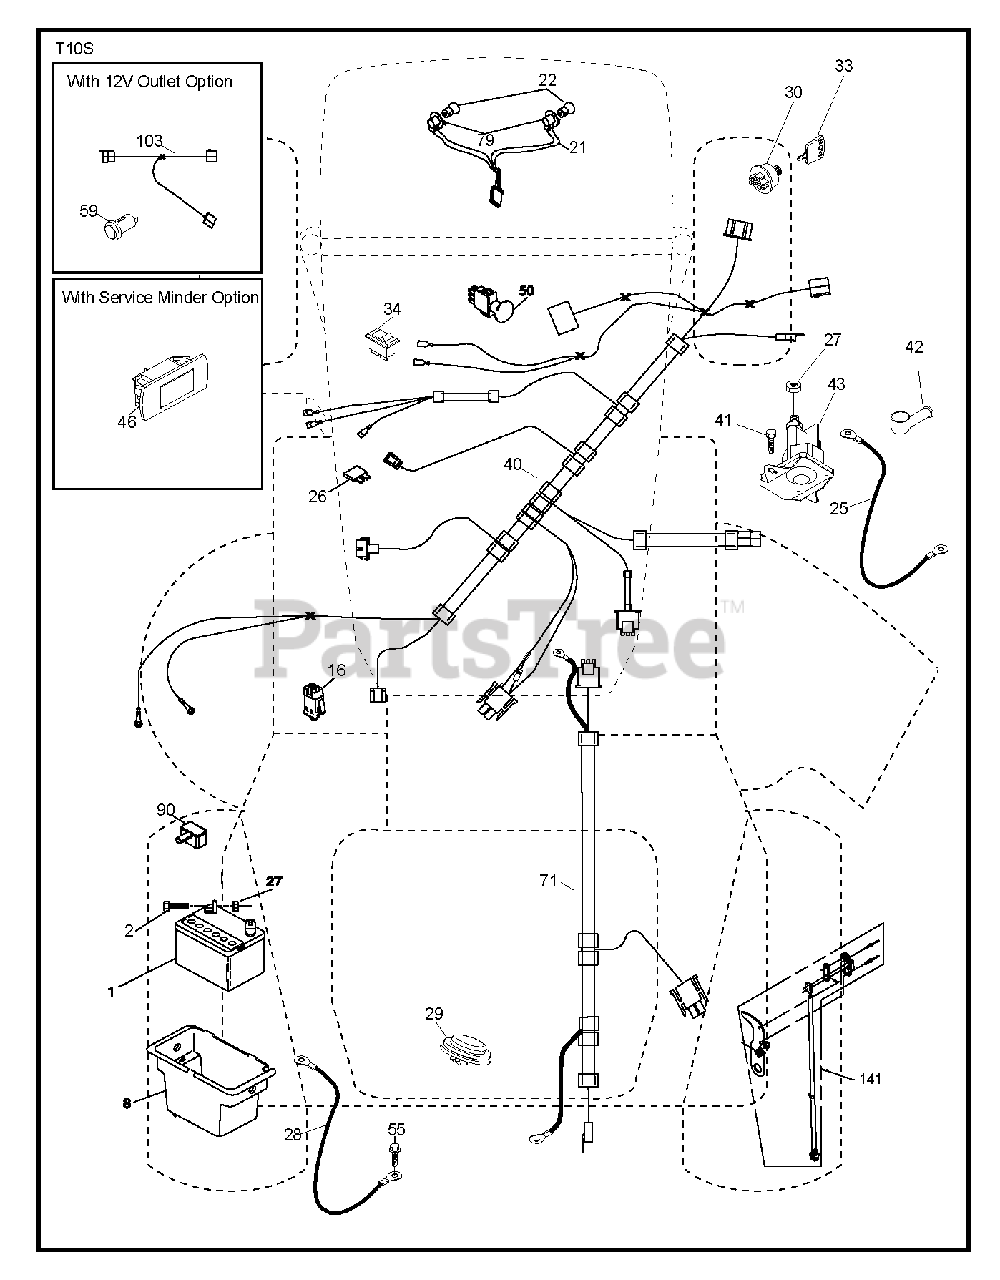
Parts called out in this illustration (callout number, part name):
1	Battery, Dry 30 Amp
2	BOLT.HEX.1/4.X.3/4.DICHROMATE
8	BOX.BATTERY.MNT.REAR.L
16	SWITCH INTERLOOK PUSH-IN
21	HARNESS.LIGHT W/4152J BULBS
25	CABLE.STARTER.6GA.BL/RED.14.
26	FUSE 20AMP
27	NUT
28	CABLE.BLACK.18"REAR.BA
29	SWITCH.SEAT.DELTA.OPC.
30	SWITCH.IGN.DELTA.W.LGH.ROS
33	KEY.CHAIN.BLISTER.PACK.GEN.INT
40	HARNESS.IGN.DASH.HUQ/P
41	SCREW
42	TERMINAL COVER
43	SOLENOID.W/BRASS.PLUNGER
46	RP GUAGE.SRVCMNDR.HRMTR.
50	RB PTO.SWITCH.8 TERMINAL.BLACK
55	SCREW 5/16"
71	HARNESS.CHASSIS.TEX.8AWG
79	BULB HOLDER ASM.
90	COVER.TERMINAL.BATTERY
141	KIT T2.ROS 71677
